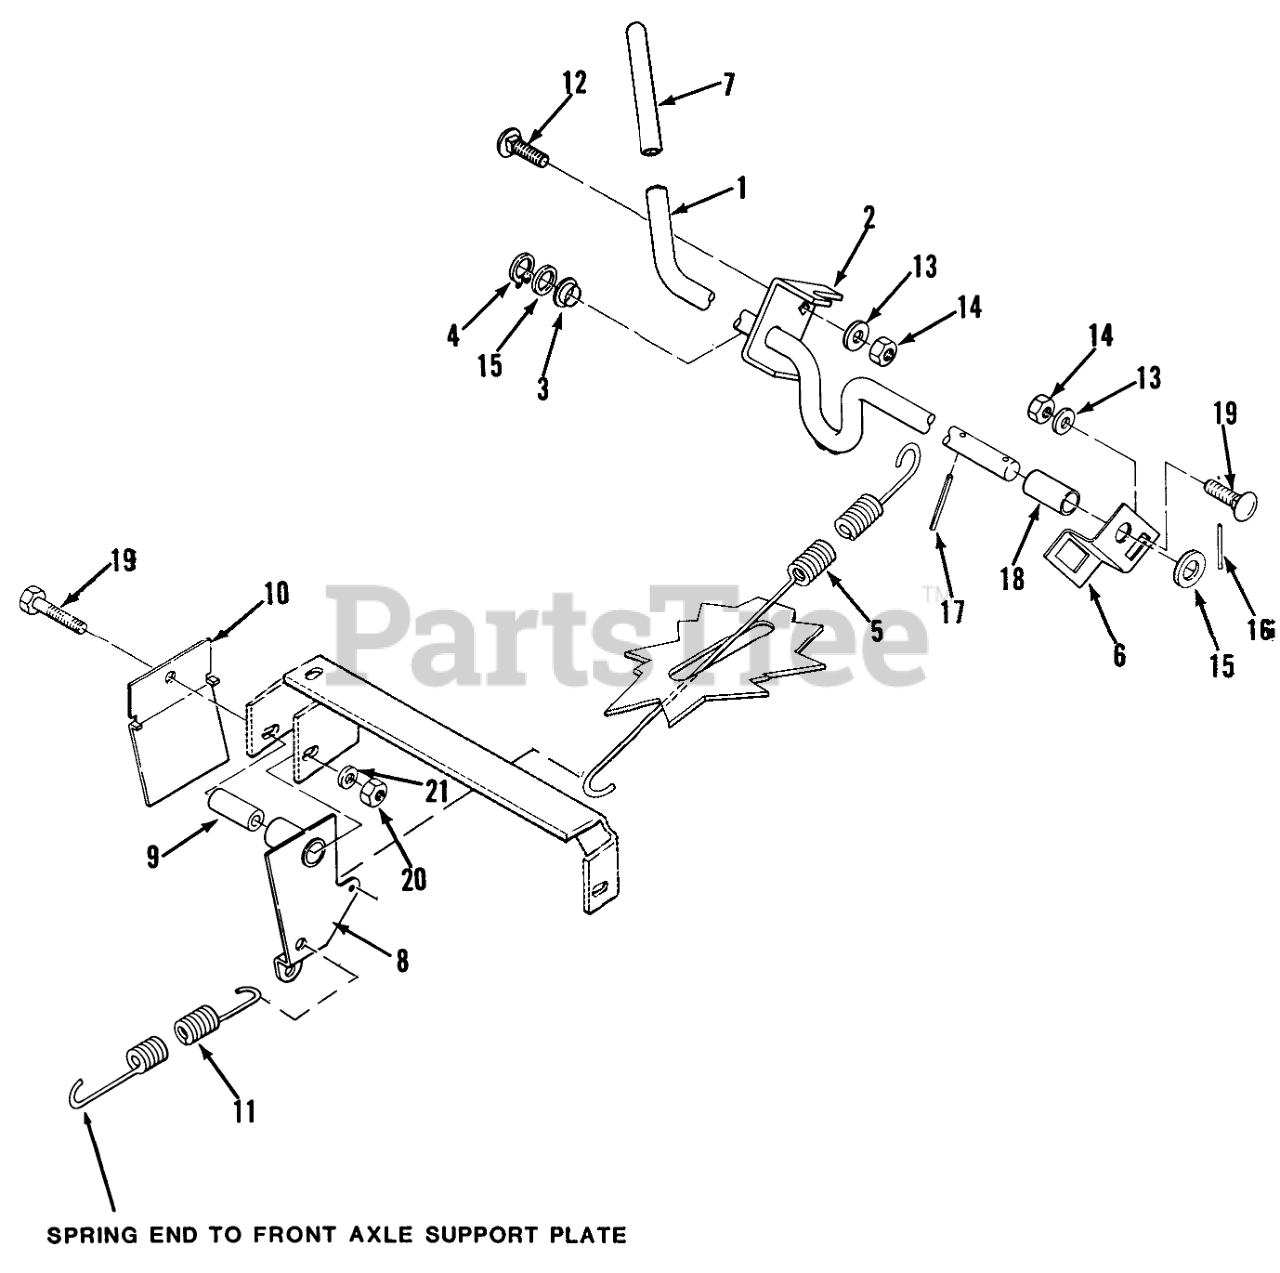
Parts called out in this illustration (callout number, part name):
1	PTO Rod Handle1
2	PTO Stop Bracket
3	BUSHING-NYLINER
4	Grip Ring
5	PTO Spring 1/4-20
6	PTO Switch Bracket
7	GRIP
8	Pivot Arm
9	Spacer
10	PLATE BELT GAGE R
11	SPRING
12	Bolt
13	WASHER
14	Nut
15	Washer
16	Pin-Roll
17	Roll Pin
18	Spacer
19	Bolt
20	NUT
21	Washer
